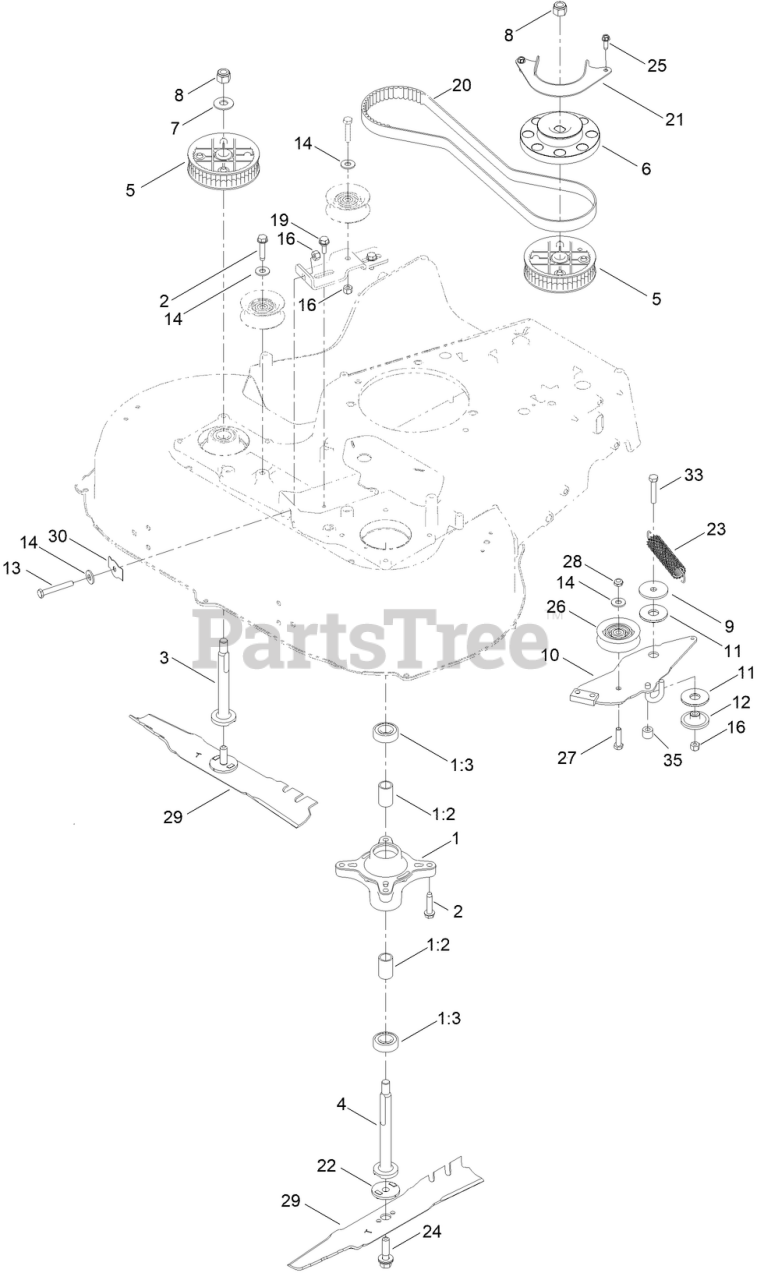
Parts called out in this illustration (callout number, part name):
1	SPINDLE ASM
1:2	SPACER
1:3	BEARING-BALL
2	SCREW-THD ROLL, HWH
3	SHAFT-SPINDLE
4	SHAFT-SPINDLE
5	SPROCKET
6	PULLEY-BRAKE, SPINDLE
7	WASHER-SPRING
8	NUT-HEX
9	WASHER-REBOUND
10	BRAKE ARM ASM
11	WASHER-FRICTION, COMPOSITE
12	SPACER
13	BOLT-TAP, HH
14	WASHER-FLAT
16	NUT-LOCK, NI
19	SCREW-SHOULDER,HWH
20	BELT-SYNCHRONOUS
21	GUIDE-BELT, SPINDLE
22	ADAPTER-BLADE
23	SPRING-EXTENSION, BRAKE
24	BOLT-BLADE
25	SCREW-HWHTF
26	PULLEY-IDLER
27	SCREW-HH
28	NUT-LOCK, NI
29	BLADE-ROTARY
30	SPRING-FLAT
33	SCREW-HH
35	HOSE-COOLANT
